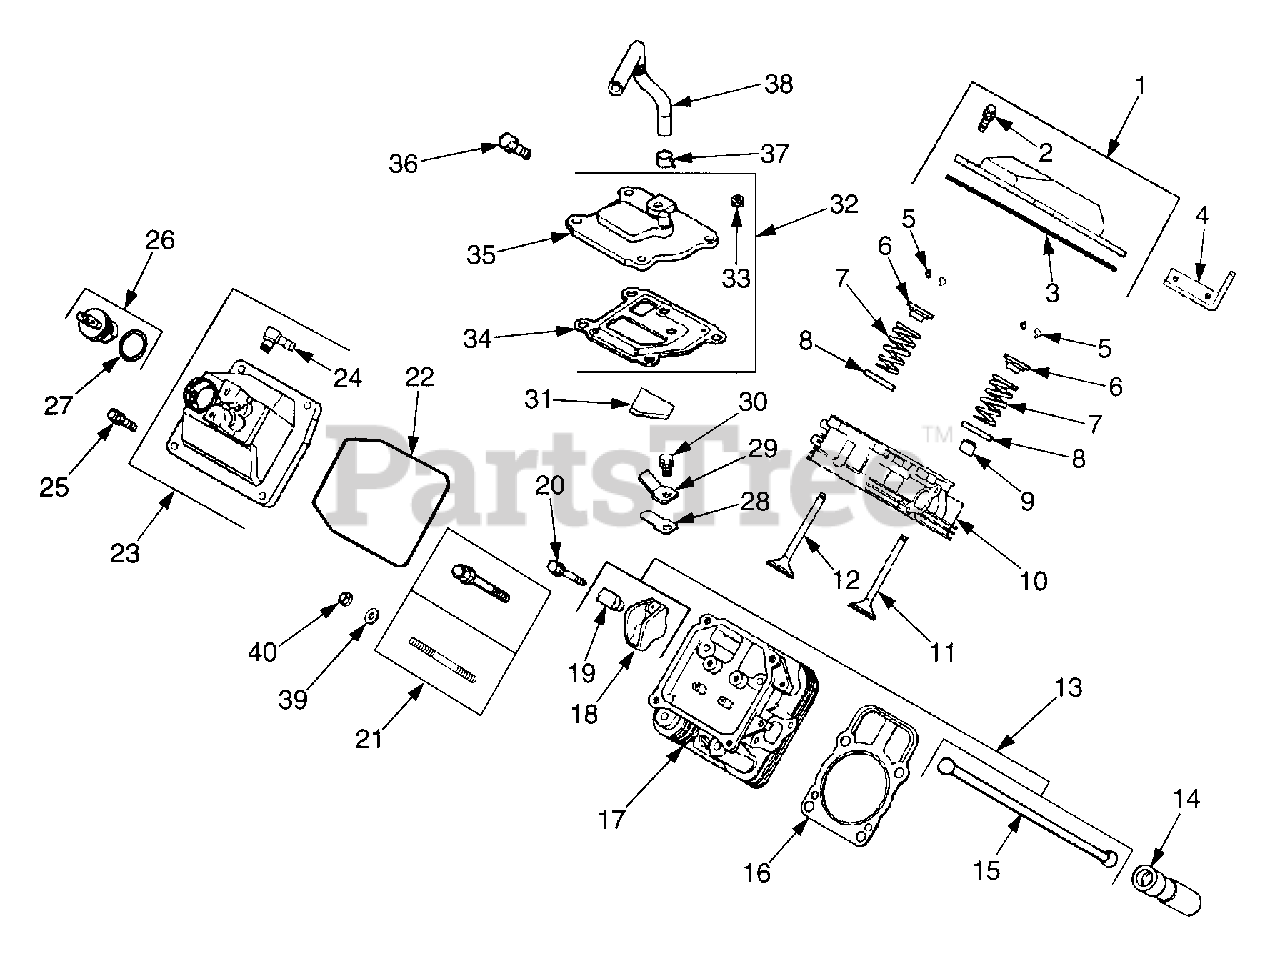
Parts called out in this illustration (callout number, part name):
1	Kit, Valve Cover
2	Screw, Shoulder
3	O-Ring, Valve Cover
4	Strap, Lifting
5	Kit, Retainer
6	Cap, Valve Spring
7	Spring, Valve
8	Retainer, Spring
9	Seal, Valve Stem
10	Head Assembly, #1 Cyl.
11	Valve, Intake (Std)
12	Valve, Exhaust (Std)
13	Kit, Valve Train
14	Lifter, Valve
16	Gasket, Cylinder Head
17	Head Assembly, #2 Cyl.
19	Pivot, Rocker Arm
20	Screw, Hex Flange M6 x 1 x 34
21	Screw, Hex Flange
22	O-Ring, Valve Cover
23	Cover, Fuel Pump Valve
24	Connector 90°.
25	Screw, Shoulder
26	Cap Assembly, Oil Fill
27	O-Ring
28	Reed, Breather
29	Retainer, Breather Reed
30	Screw, Hex Flange M5 x 0.8 x 10
31	Filter, Breather
32	Kit, Breather
33	Plug, Allen Head 1/8 NPTF
34	Gasket, Breather
35	Cover, Breather
36	Screw, Hex Flange M6 x 1.0 x 20
37	Clamp, Breather
38	Hose, Breather
39	Washer, Flat, 8mm
40	Nut, Hex Flange, M8 x 1.25
